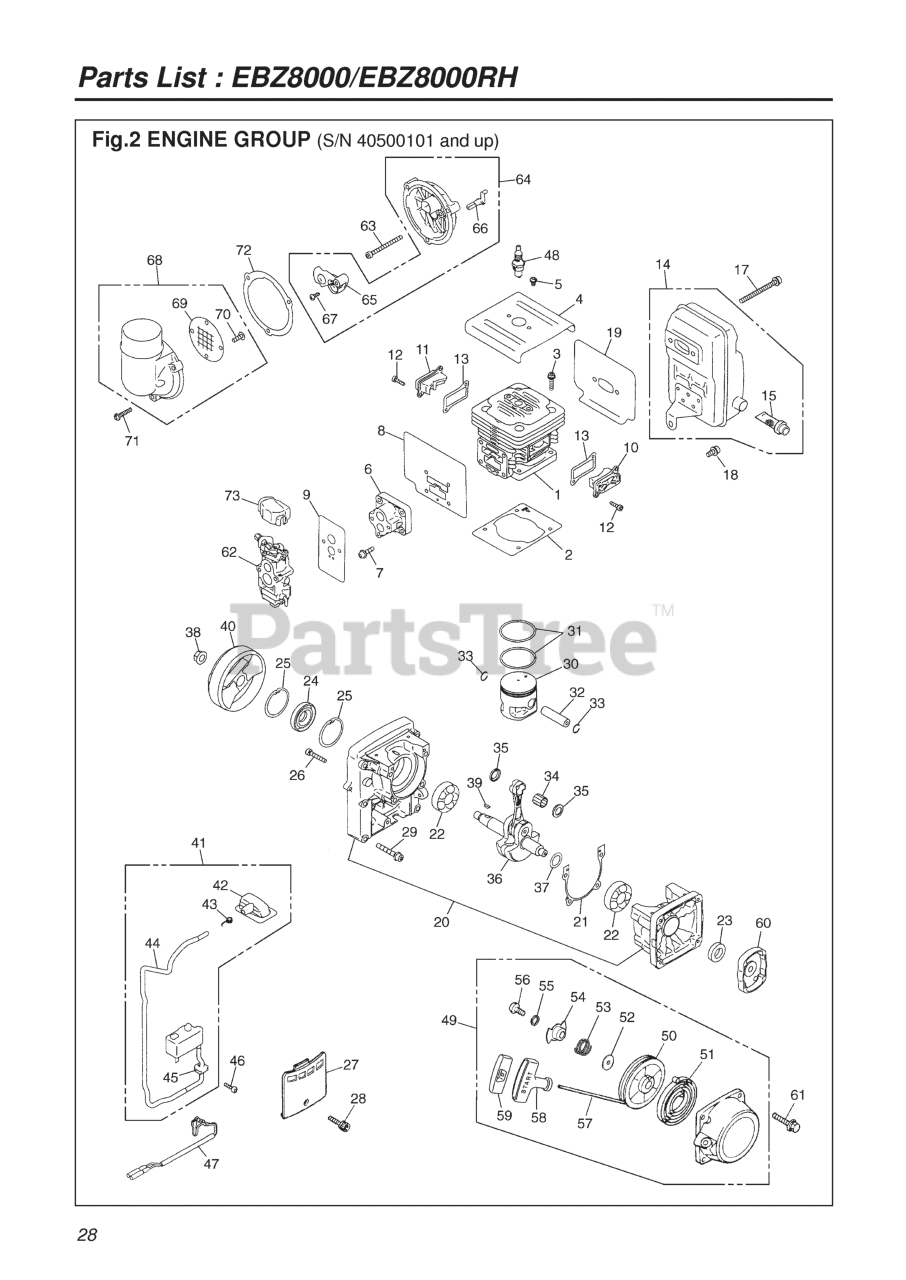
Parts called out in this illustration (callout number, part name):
2	GASKET, BASE
3	BOLT
4	PLATE, CYL
5	SCREW TORX
6	INSULATOR
7	BOLT TORX
8	GASKET, INSULATOR
9	GASKET, CARB.
10	COVER, TR-S
11	COVER,TR-F
12	BOLT TORX
14	MUFFLER ASSY.
15	ARRESTER
17	BOLT
18	BOLT
19	GASKET, MUFFLER (USE -15C1)
20	CRANKCASE-CASE
21	GASKET, CASE
22	BEARING
23	SEAL
24	SEAL
25	SNAP RING
26	BOLT
27	COVER
28	BOLT TORX
29	BOLT TORX
30	PISTON
31	RING
32	PIN
33	SNAP RING
34	BEARING
35	WASHER
38	NUT, M10
39	KEY
40	ROTOR
41	COIL-A
42	CAP
45	GROMMET
46	BOLT TORX
47	CORD-C
51	SPRING
56	SCREW
57	ROPE
58	KNOB
59	COVER KNOB
62	CARBURETOR-A (WYA-44)
63	BOLT
66	LEVER
69	SCREEN
70	SCREW
71	SCREW
72	GASKET,CUP
73	COVER
